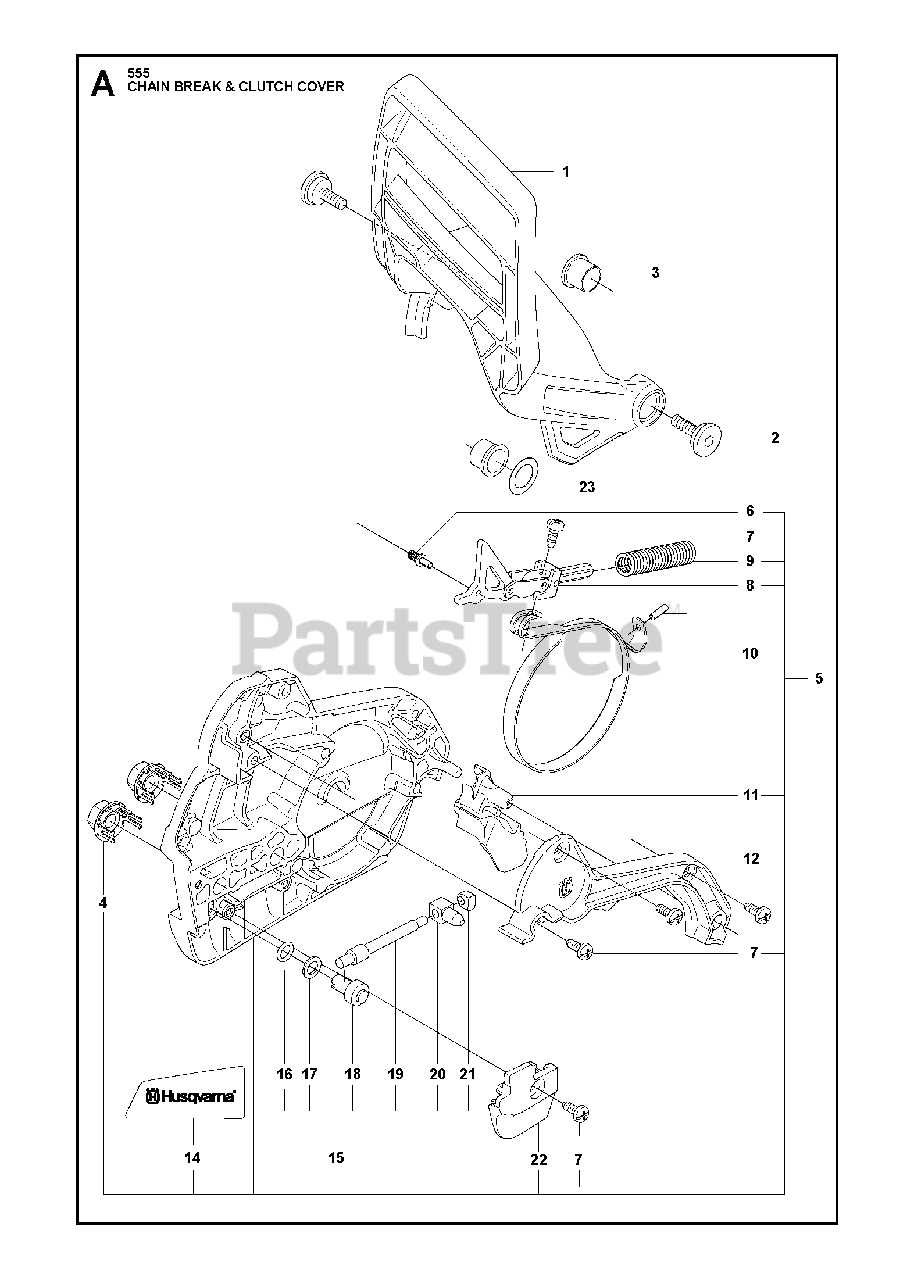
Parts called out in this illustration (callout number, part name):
1	HAND GUARD
4	NUT RETAINER ASSY
5	CLUTCH COVER ASSY
6	PIN
7	SCREW
8	KNEE JOINT ASSY
9	SPRING
10	BRAKE BAND ASSY
11	GUARD
12	COVER
14	LABEL
15	CHAIN TENSIONER KIT
16	O-RING
17	WASHER
18	WORM SCREW
20	PAWL
21	WORM WHEEL
22	CHAIN GUIDE
23	WASHER STEEL
